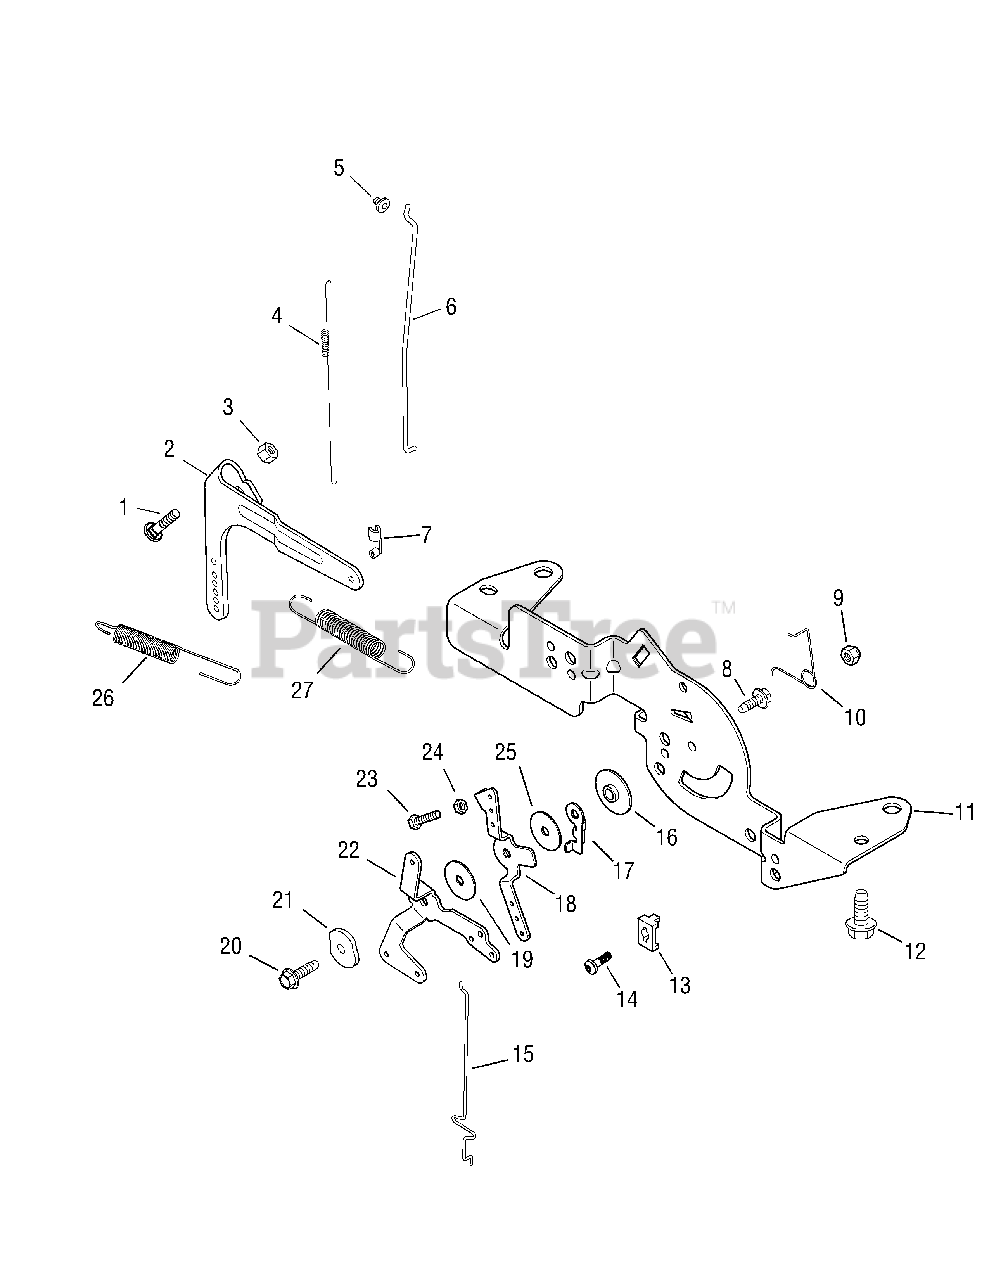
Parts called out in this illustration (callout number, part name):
1	Round Head Square Neck Bolt
2	Governor Lever
3	Hex Flange Nut, M6 x 1.0
4	Linkage Spring
5	Linkage Retaining Bushing
6	Throttle Linkage
7	Throttle Linkage Bushing
8	Hex Flange Screw, M5 x 0.8 x 16
9	Hex Lock Nut, M5 x 0.8
10	Choke Return Spring
11	Control Bracket
12	Hex Flange Screw, M6 x 1.0 x 16
13	Dual Conduit Clamp
14	Thread Forming Screw
15	Choke Linkage
16	Control Assembly Spacer
17	Throttle Actuator Lever
18	Throttle Control Lever
19	Washer, 5.5 mm
20	Hex Flange Screw, M5 x 0.8 x 20
21	Spring Washer, 1.4
23	Hex Cap Screw, M4 x 0.7 x 25
24	Hex Nut, M4 x 0.7
26	Governor Spring
27	Governor Spring
